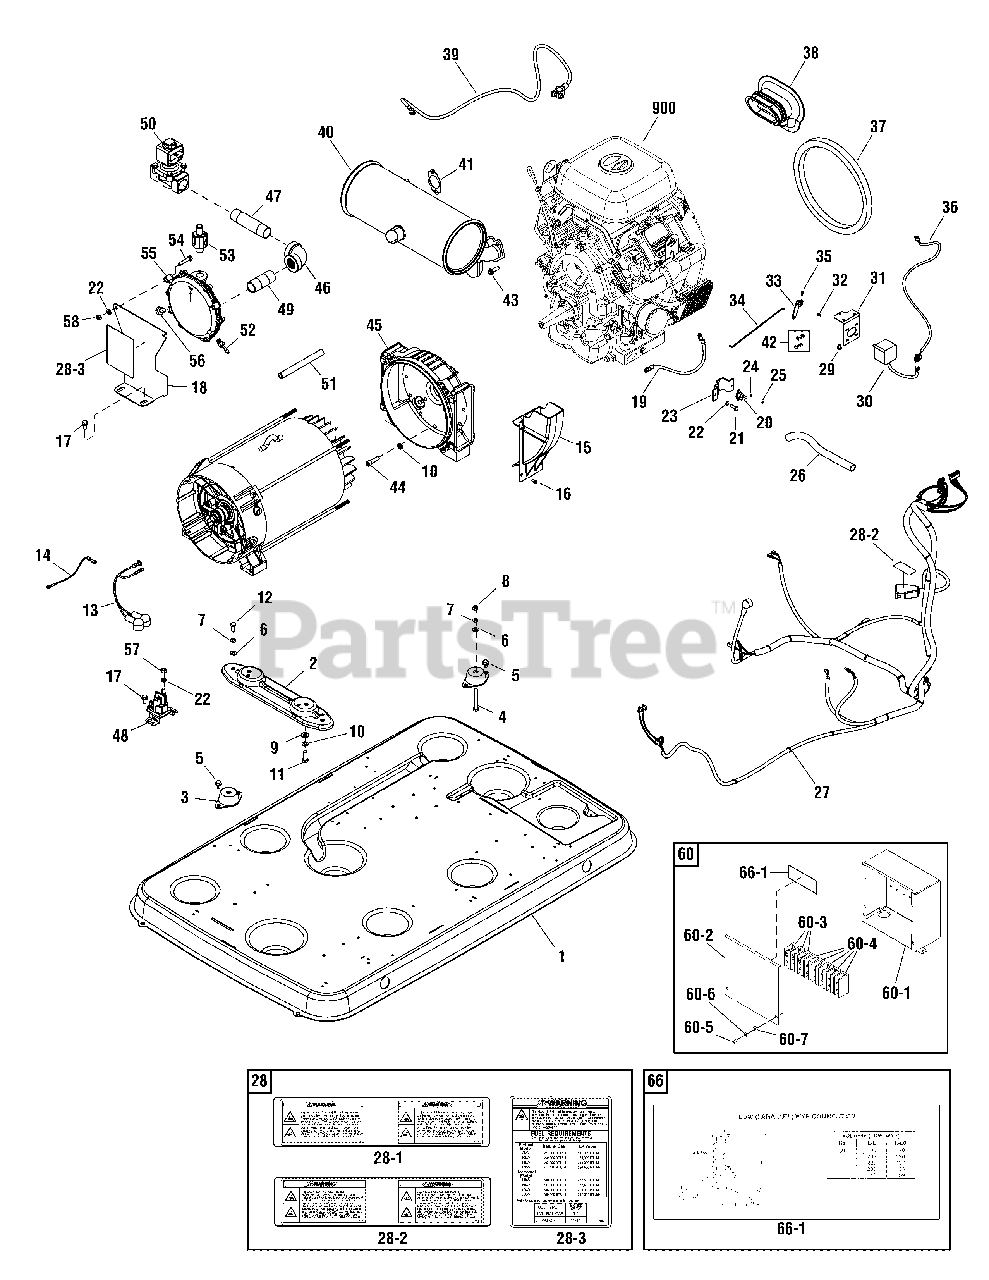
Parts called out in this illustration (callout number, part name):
1	BASE
3	MOUNT-VIBRATION
4	* CAPSCREW, Hex Head, 5/16-18 x 2-1/2
6	* WASHER, Flat, M8
7	* WASHER, Lock, M8
8	* NUT, 5/16-18
9	* WASHER, Flat, M10
10	* WASHER, Lock, 3/8
11	* CAPSCREW, Hex Head, 3/8-16 x 1
12	* CAPSCREW, Hex Head, 5/16-18 x 3/4
14	WIRE-GROUND RELAY
16	* SCREW, M5-0.8 x 10
17	BOLT
18	BRACKET
21	CAPSCREW, Hex Head, M6-1.0 x 16
22	* WASHER, Lock, 1/4
24	* WASHER, Shakeproof, #4
25	SCREW
28	DECAL SHEET-WARNINGS
28-1	DECAL-WARNING, EXPLOSION
28-2	DECAL-WARNING, EXPLOSION
28-3	DECAL-FUEL REQUIREMENTS
30	STEPPER MOTOR
31	BRACKET
32	* CAPSCREW, Hex Head, M3-0.5 x 6
33	ARM-LINK
35	* CAPSCREW, Hex Head, M3-0.5 x 8
39	WIRE-BATTERY, GROUND
43	* SCREW, M8 x 25
48	SOLENOID-STARTER
53	VALVE-LP/NG SWITCH
54	* CAPSCREW, Hex Head, M6-1.0 x 30
55	REGULATOR
57	* NUT, 1/4-20
58	* NUT, Hex, M6-1
60	TERMINATION BOX
60-2	COVER
60-5	* CAPSCREW, Hex Head, 1/4-20 x 3/4
60-6	* WASHER, Lock, 1/4
60-7	* WASHER, Flat, 1/4
66	DECAL SHEET-VOLTAGE
66-1	DECAL-VOLTAGE
900	** ENGINE
